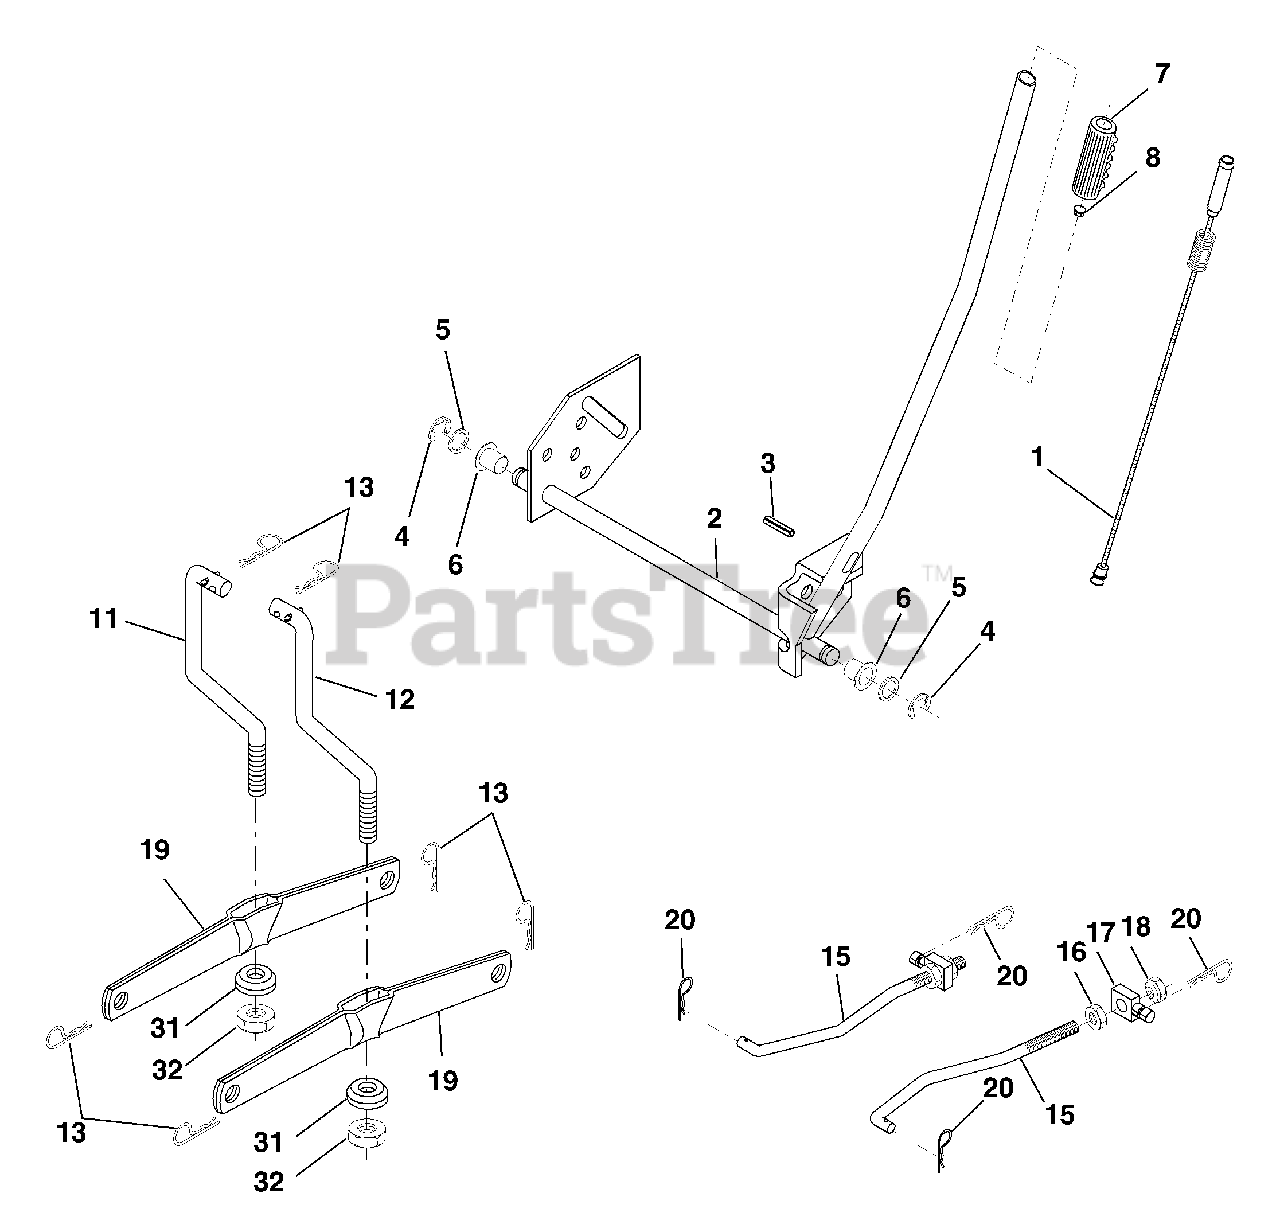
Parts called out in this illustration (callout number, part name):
1	Wire Asm Inner/Sprg w/Plunger
2	Shaft Asm Lift
3	Pin Groove
4	E Ring #5133-62
5	Washer 21/32 x 1 x 21 Ga.
6	Bearing Nylon
7	Grip Handle
8	Button Plunger
11	Link Lift Lh
12	Link Lift Rh
13	Retainer Spring
15	Link Front
16	Nut Jam Hex 1/2-13 unc
17	Trunnion Blk Zinc
18	Nut Lock w/Wsh 1/2-13 unc
19	Arm Suspension Rear
20	Pin Cotter 7/16 Bowtie Lock
31	Bearing Pvt Lift
32	Nut Crownlock 3/8-24
